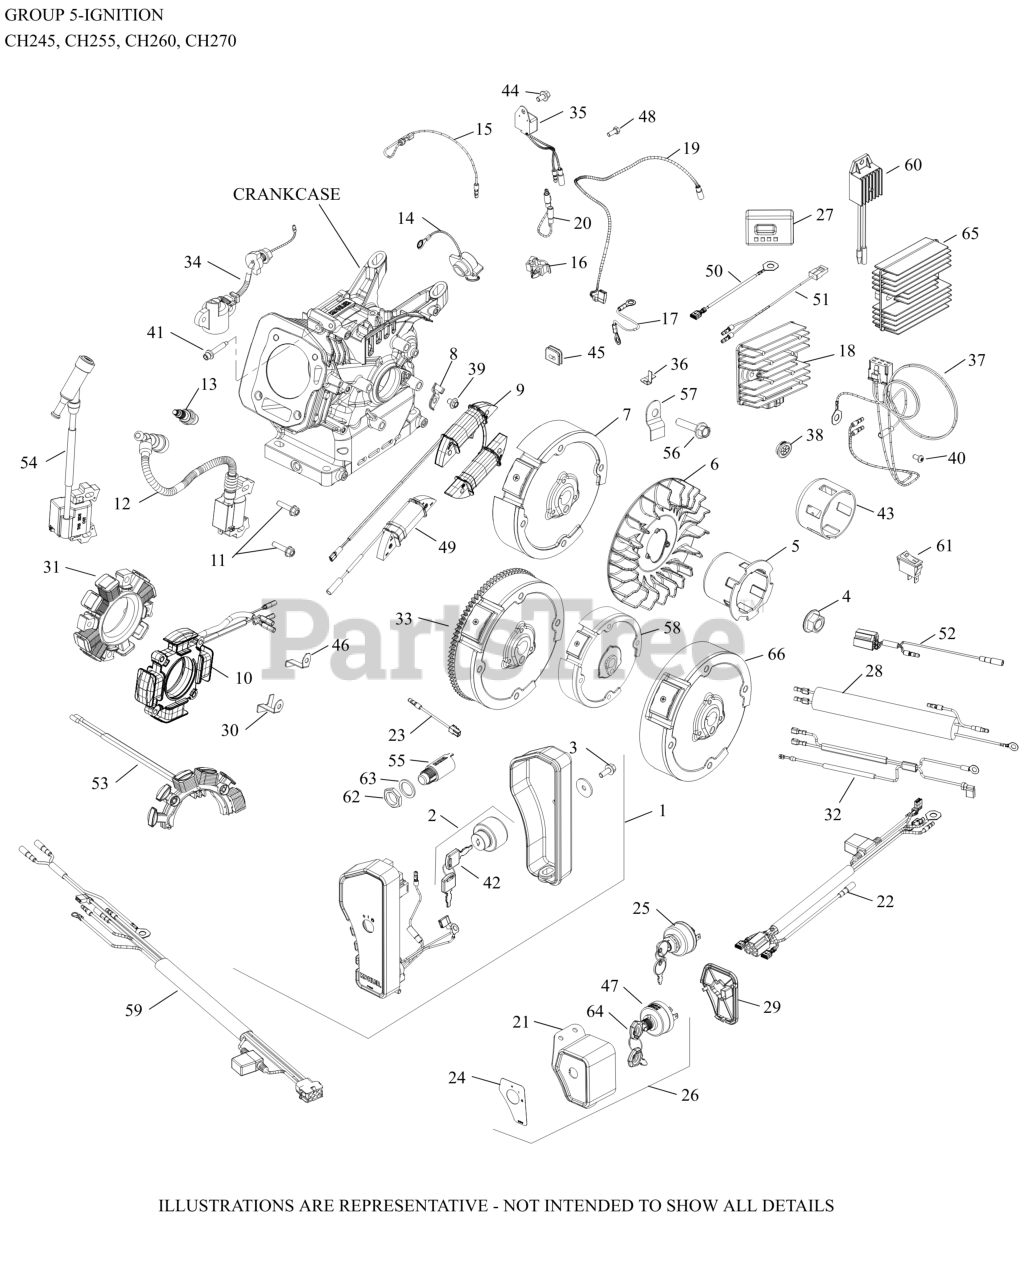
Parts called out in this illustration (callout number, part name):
3	SCREW, HEX FLANGE (M6)-USE 25 086 433-S
4	NUT, FLYWHEEL
5	CUP, STARTER DRIVE
6	FAN, FLYWHEEL
7	FLYWHEEL ASSY,CAST IRON-(#1702528S)
11	SCREW, M6 X 25-(#25086436S)
12	MODULE, IGNITION
13	SPARK PLUG
16	CLIP, WIRE HARNESS
19	LEAD, GROUND TO KILL
28	LEAD, MICROSWITCH
